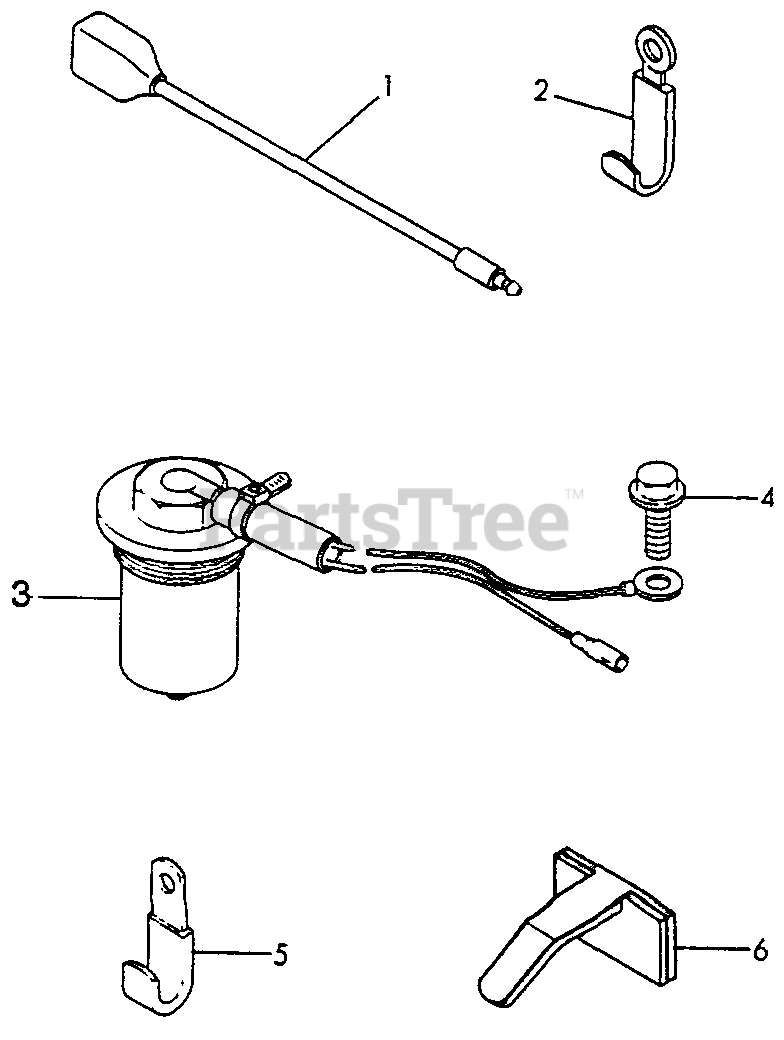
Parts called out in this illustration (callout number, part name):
1	WIRE
2	CLAMP
3	SENSOR, OIL LEVEL
4	BOLT - 6×12
5	CLAMP
6	CLAMP
